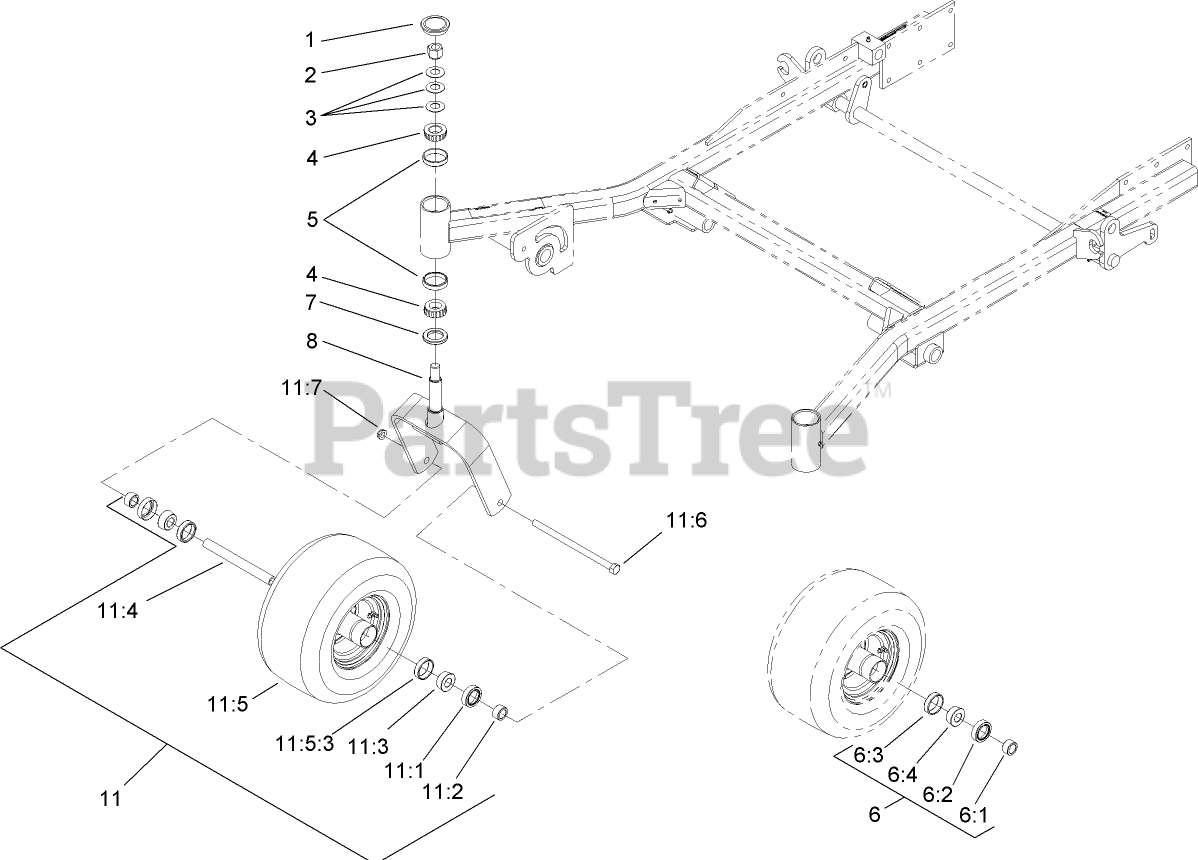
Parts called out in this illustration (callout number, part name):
1	CAP-GREASE
2	NUT-LOCK, NI
3	WASHER-BELLVILLE
4	BEARING-CONE, TAPERED
5	BEARING-CUP, TAPERED
6	CASTER WHEEL BEARING KIT
6:1	SPACER-BEARING
6:2	SEAL-BEARING
6:3	BEARING-CUP
6:4	BEARING-CONE, TAPER
7	SEAL-GREASE
8	CASTER-FORK
11	CASTOR WHEEL ASM
11:1	SEAL-BEARING
11:2	SPACER-BEARING
11:3	BEARING-CONE, TAPER
11:4	SPACER-CASTER, FRONT
11:5	WHEEL AND TIRE ASM (SEMI-PNEUMATIC)
11:5:3	BEARING-CUP
11:6	SCREW-HH
11:7	NUT-LOCK, NI
